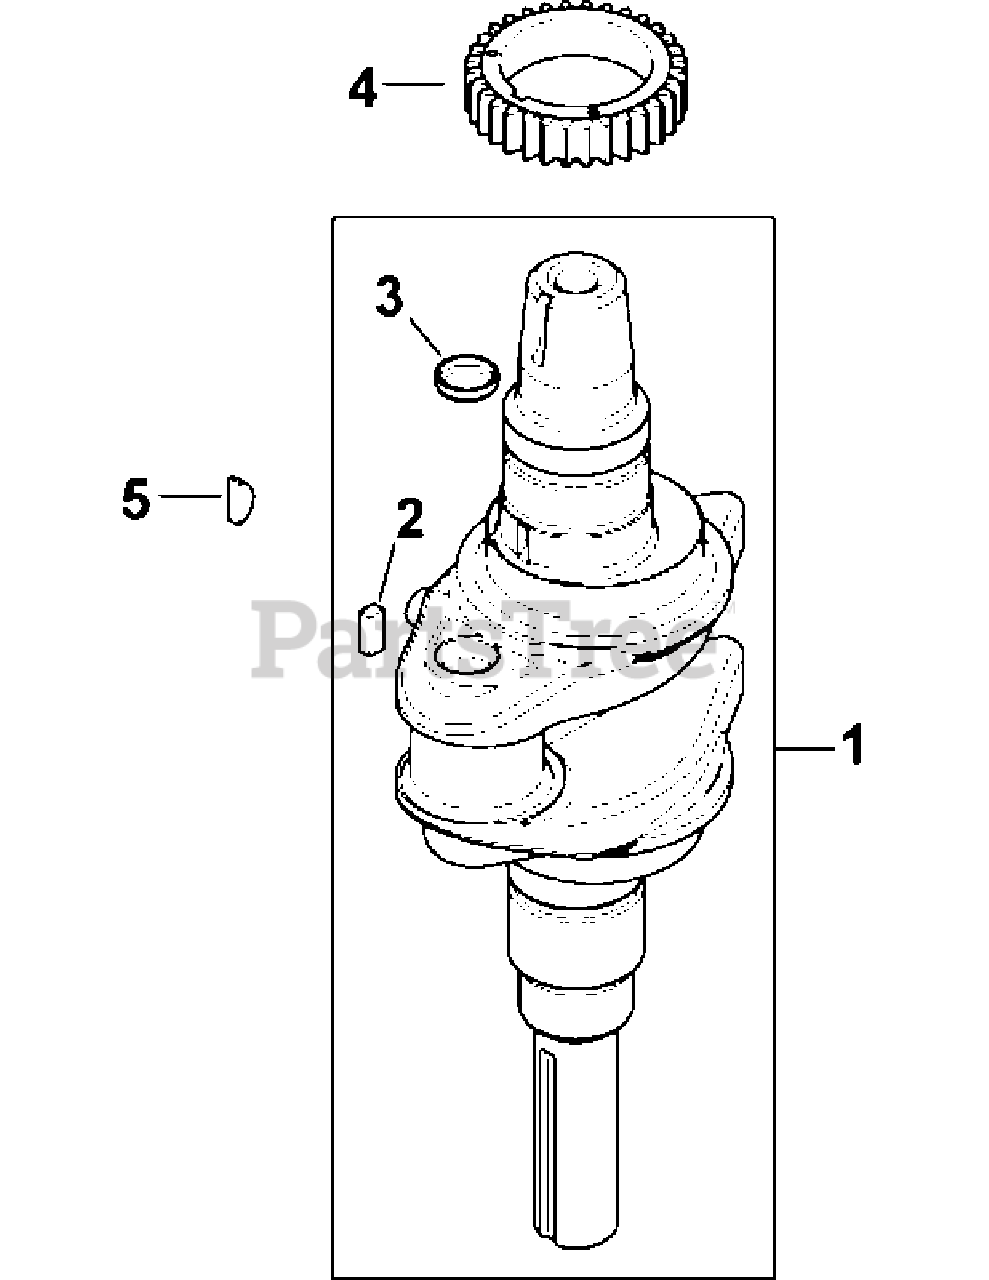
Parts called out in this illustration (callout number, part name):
1	Crankshaft Kit
2	Key,Straight Flywheel
4	Gear, Crankshaft
5	Key, 3/16" x 5/8"
